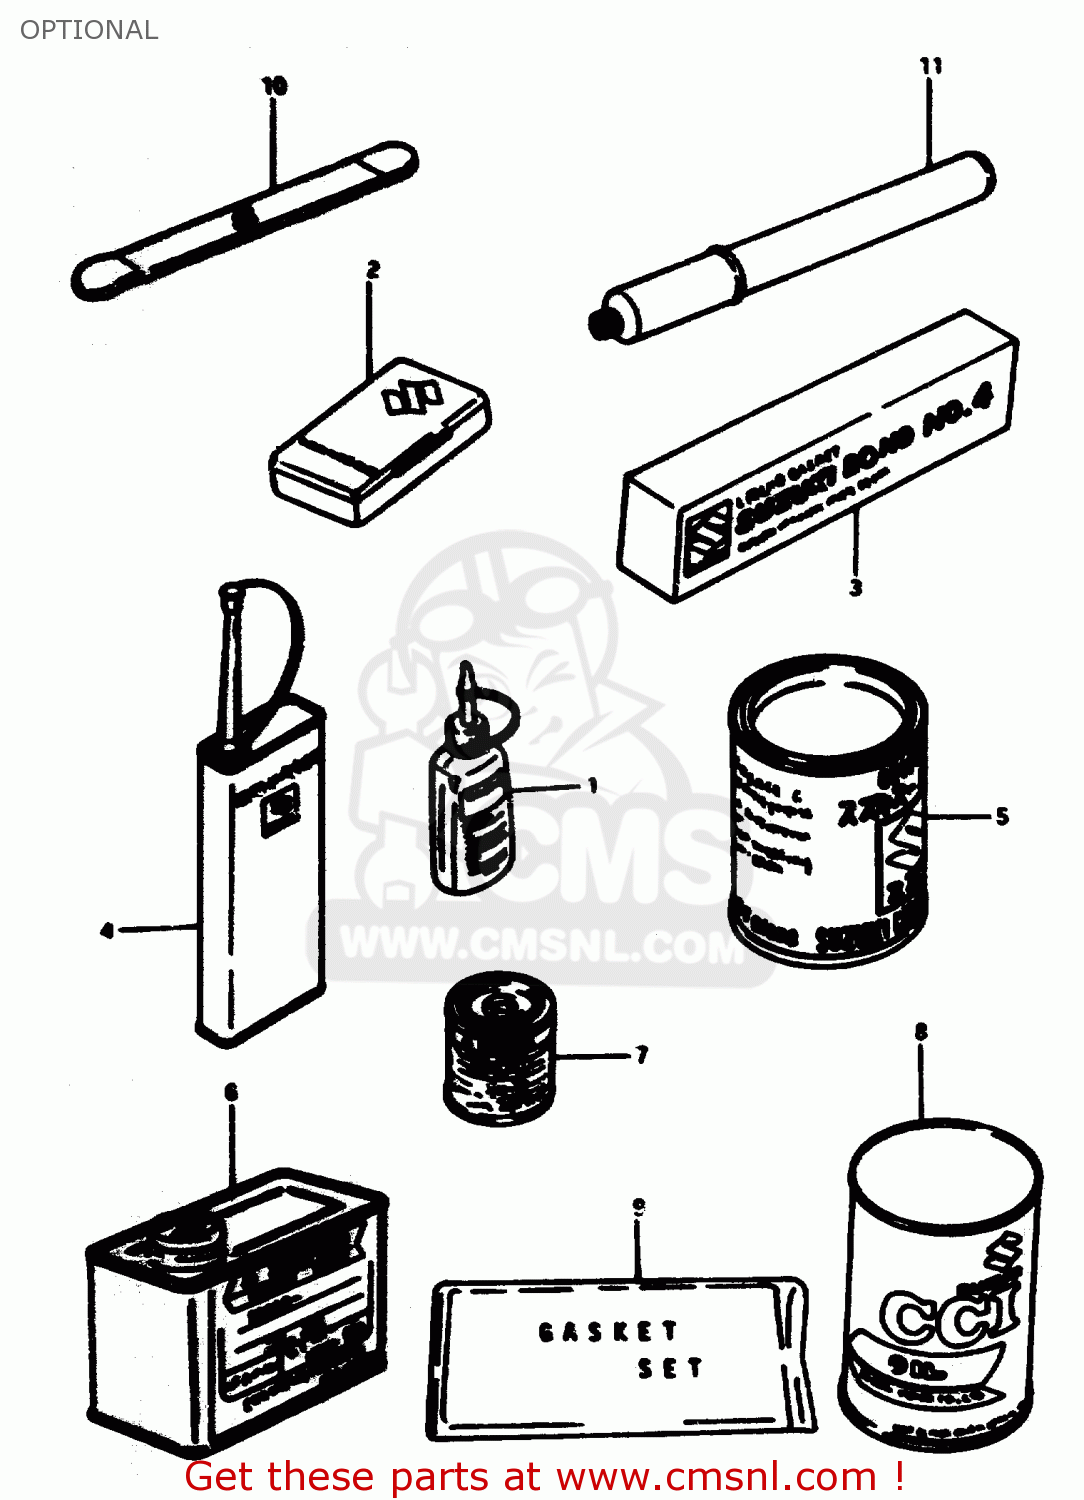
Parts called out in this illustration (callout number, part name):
1	THREAD LOCK NO.1303B PURPL 50G
2	TUBE REPARING TOOL
3	BOND 1104
4	THREAD LOCK NO.1401 CLEAR 200G
5	GREASE(C)EP2 LITHIUM 150G
6	PAINT (BLACK)
7	PAINT,BLACK
8	CCI OIL
9	GASKET SET (MCA)
10	LEVER,TIRE
11	INFLATOR, AIR
